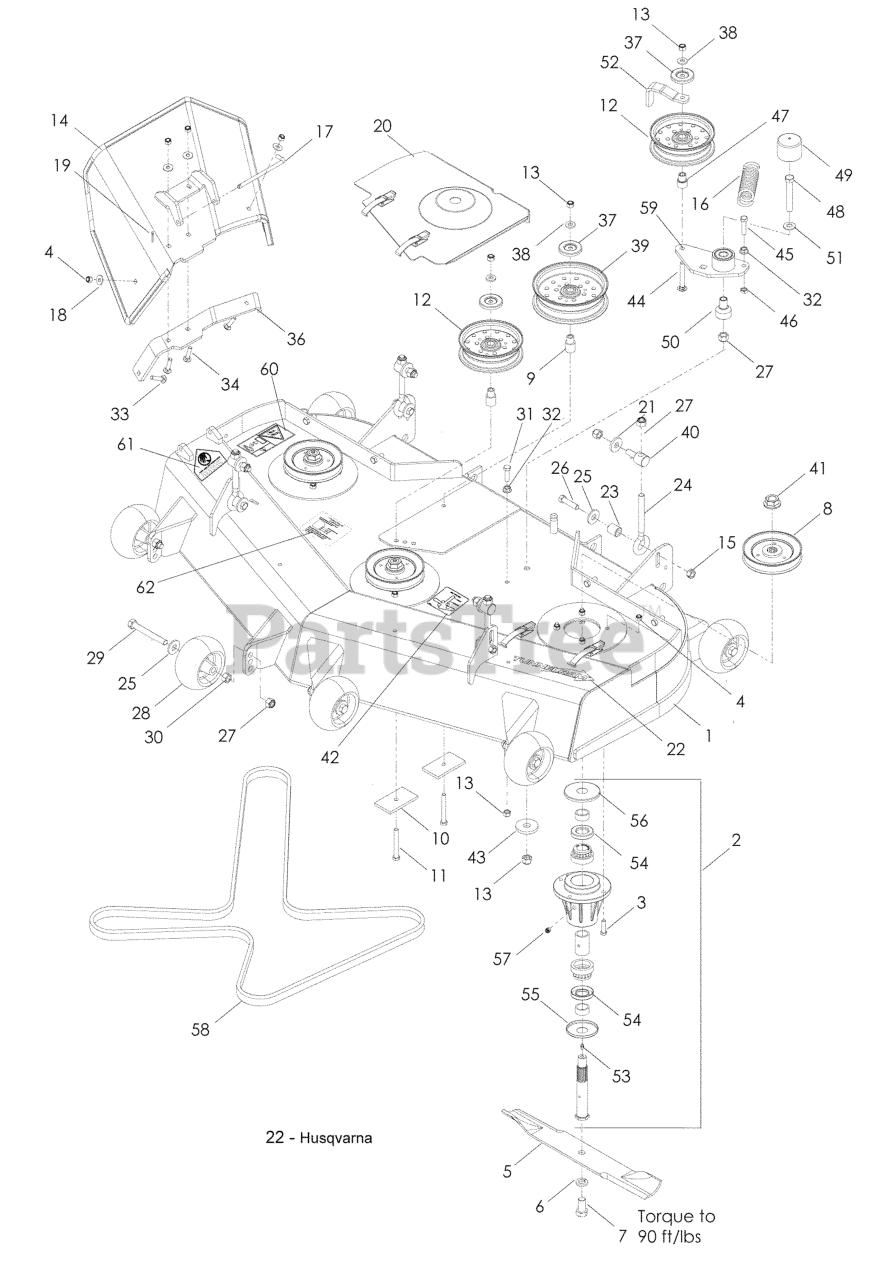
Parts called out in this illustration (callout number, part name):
1	DECK W/DECALS 52" HUS
2	HOUSING ASM, 52/61
3	HCS 5/16C X 1 1/4
4	NUT 5/16 NYLOC
5	BLADE OEM 18"
6	LOCKWASHER 5/8
7	HCS 5/8F X 1 1/4
8	PULLEY, 52
9	IDLER BUSHING
10	SUPPORT PLATE
11	HCS 3/8C X 3
12	IDLER PULLEY
13	NUT 3/8-16 NYLOC
14	CHUTE, RUBBER DISCHARGE 52/61"
15	NUT 7/16C CENTERLOCK
17	PIN, CHUTE PIVOT
18	WASHER 5/16 FLAT
19	RP_COTTER PIN 1/8 X 3/4
20	52" BELT SHIELD ASM - RH
21	WASHER-.533IDX1.37OD
22	DECAL, TUNNEL RAM 8"
25	WASH USS FLAT 1/2
26	HCS 7/16 - 14 X 1 3/4
27	NUT 1/2-13 HEX NYLOC ZD
28	GAUGE WHEEL
29	HCS 1/2-13 X 4 GR 5 ZD
30	NUT HEX 1/2
31	HCS 3/8C X 1 1/4 GR5
32	NUT 3/8C WHIZ
33	BOLT, CARRIAGE 5/16X1-1/4
34	RHSNB 5/16-18 X 1-1/2 GR 5 ZD
35	PIVOT BRACKET - RUBBER CHUTE
36	BRACKET, REINF-CHUTE
37	DUST SHIELD
38	WASHER, 3/8 THICK
39	PULLEY - IDLER, 6IN WIDE
40	SWIVEL, DECK HEIGHT ADJ
41	NUT FLANGE 3/4-16
42	DECAL, BELT ROUTING
43	WASHER, SUPPORT
44	RHSNB 3/8-16 X 2.75
45	HCS 3/8-16 X 1-1/2
46	NUT 3/8-16 HEX JAM
47	BUSHING, IDLER
48	HCS 1/2C X 3 1/4
49	CAP, VINYL
50	PIVOT, BEARING
51	CONTACT BELLSPR 1/2
52	GUIDE, BELT
53	ZERK
54	SHAFT SEAL
55	BOTTOM DUST CAP
56	TOP DUST CAP
57	PLUG-VENTED
58	BELT, DECK
59	ARM-IDLER W/BRG
60	DECAL, EURO SEVERING
61	DECAL, CPSC
62	DECAL, ANTI SCALP
